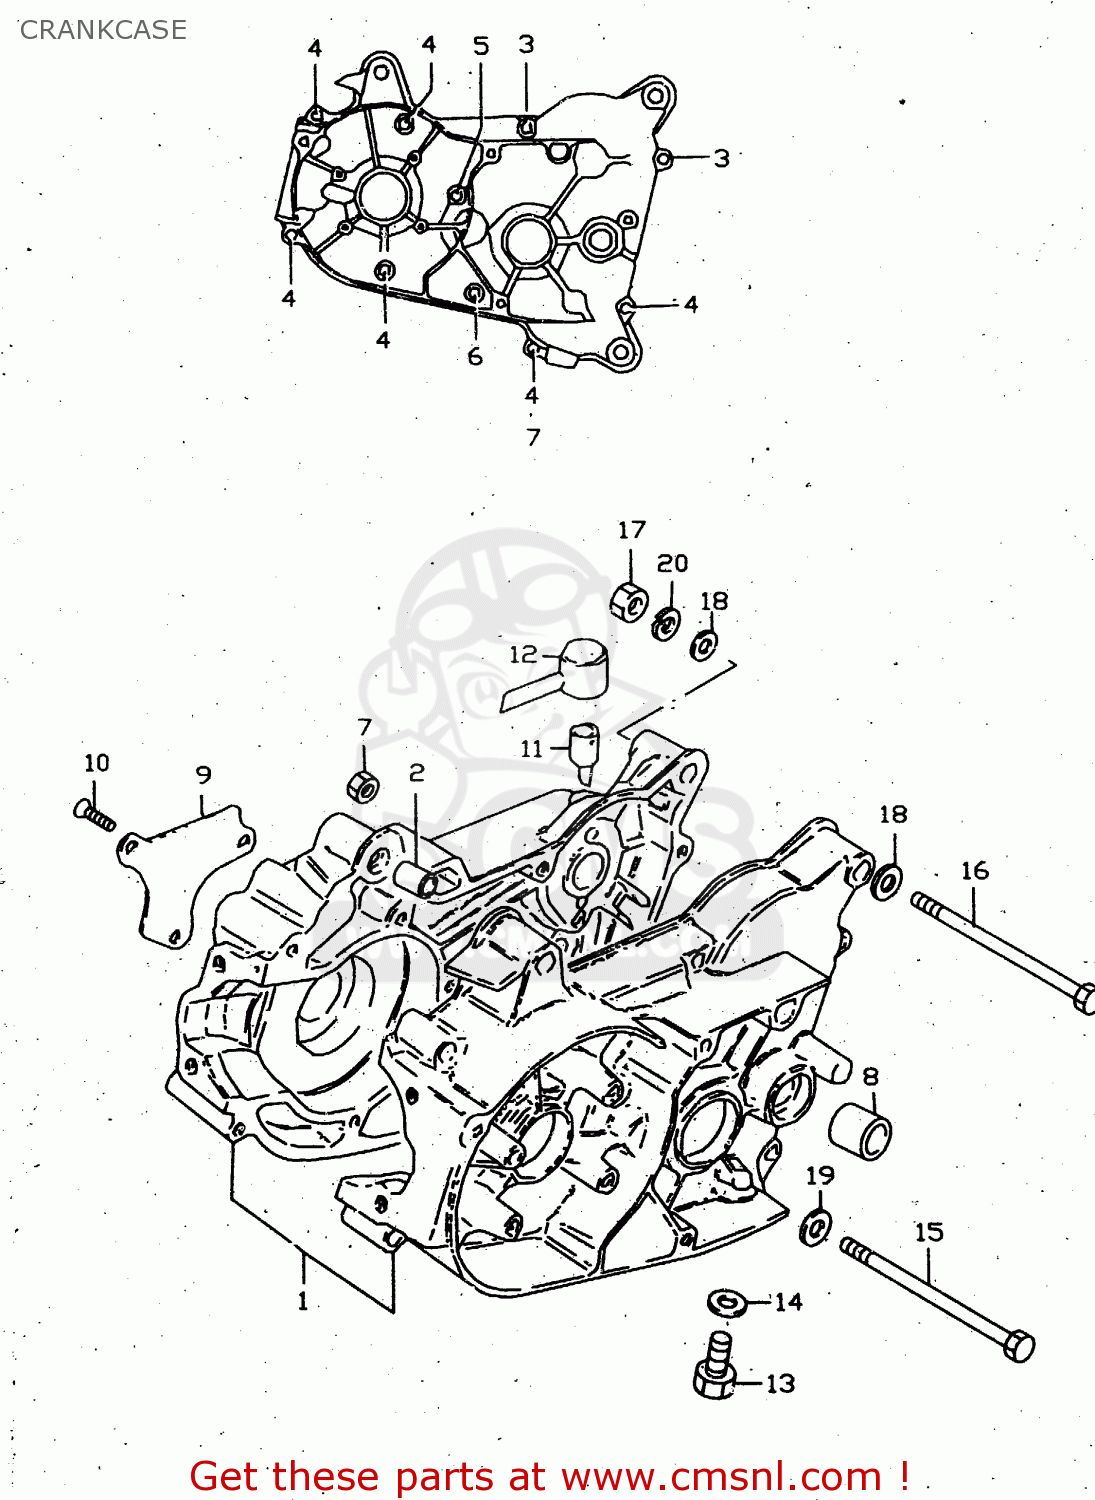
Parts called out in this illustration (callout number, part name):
1	CRANKCASE SET
2	PIN
3	SCREW 6X30
4	SCREW
5	SCREW
6	SCREW
7	NUT 6MM
8	BUSH
9	PLATE,OIL RESERVOIR
10	SCREW,UPPER
11	PLUG,T/M BREATHER
12	GASKET (NAS)
13	PLUG
14	GASKET(10X14X3.6) (NAS)
15	BOLT
16	BOLT
17	NUT
18	WASHER
19	WASHER(8.5X22X3.2)
20	LOCK WASHER
